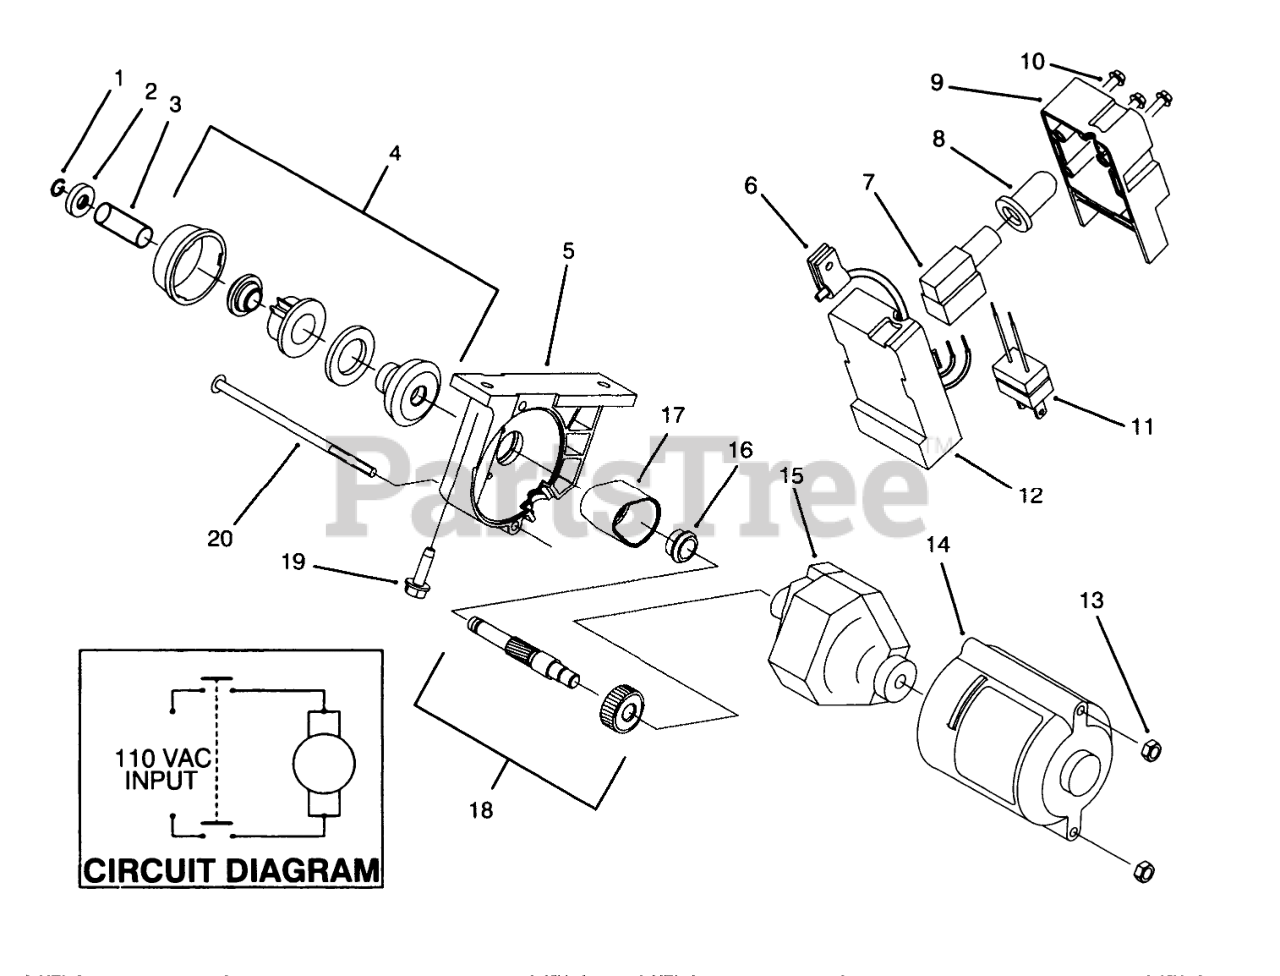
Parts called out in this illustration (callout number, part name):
1	RING-LOCK
2	PINION STOP
3	SPRING
4	Pinion ASM
5	HOUSING
6	CLAMP
7	SWITCH-STARTER
8	BOOT-SWITCH
9	Cap-Switch Housing
10	SCREW-PLASTITE
11	Plug
12	OBS BASE X
13	NUT-LOCK, NI
14	HOUSING - LOWER STARTER
15	STARTER MOTOR ASSEMBLY
16	BUSHING
17	COVER-GEAR
18	Asm-shaft & Gear
19	SCREW
